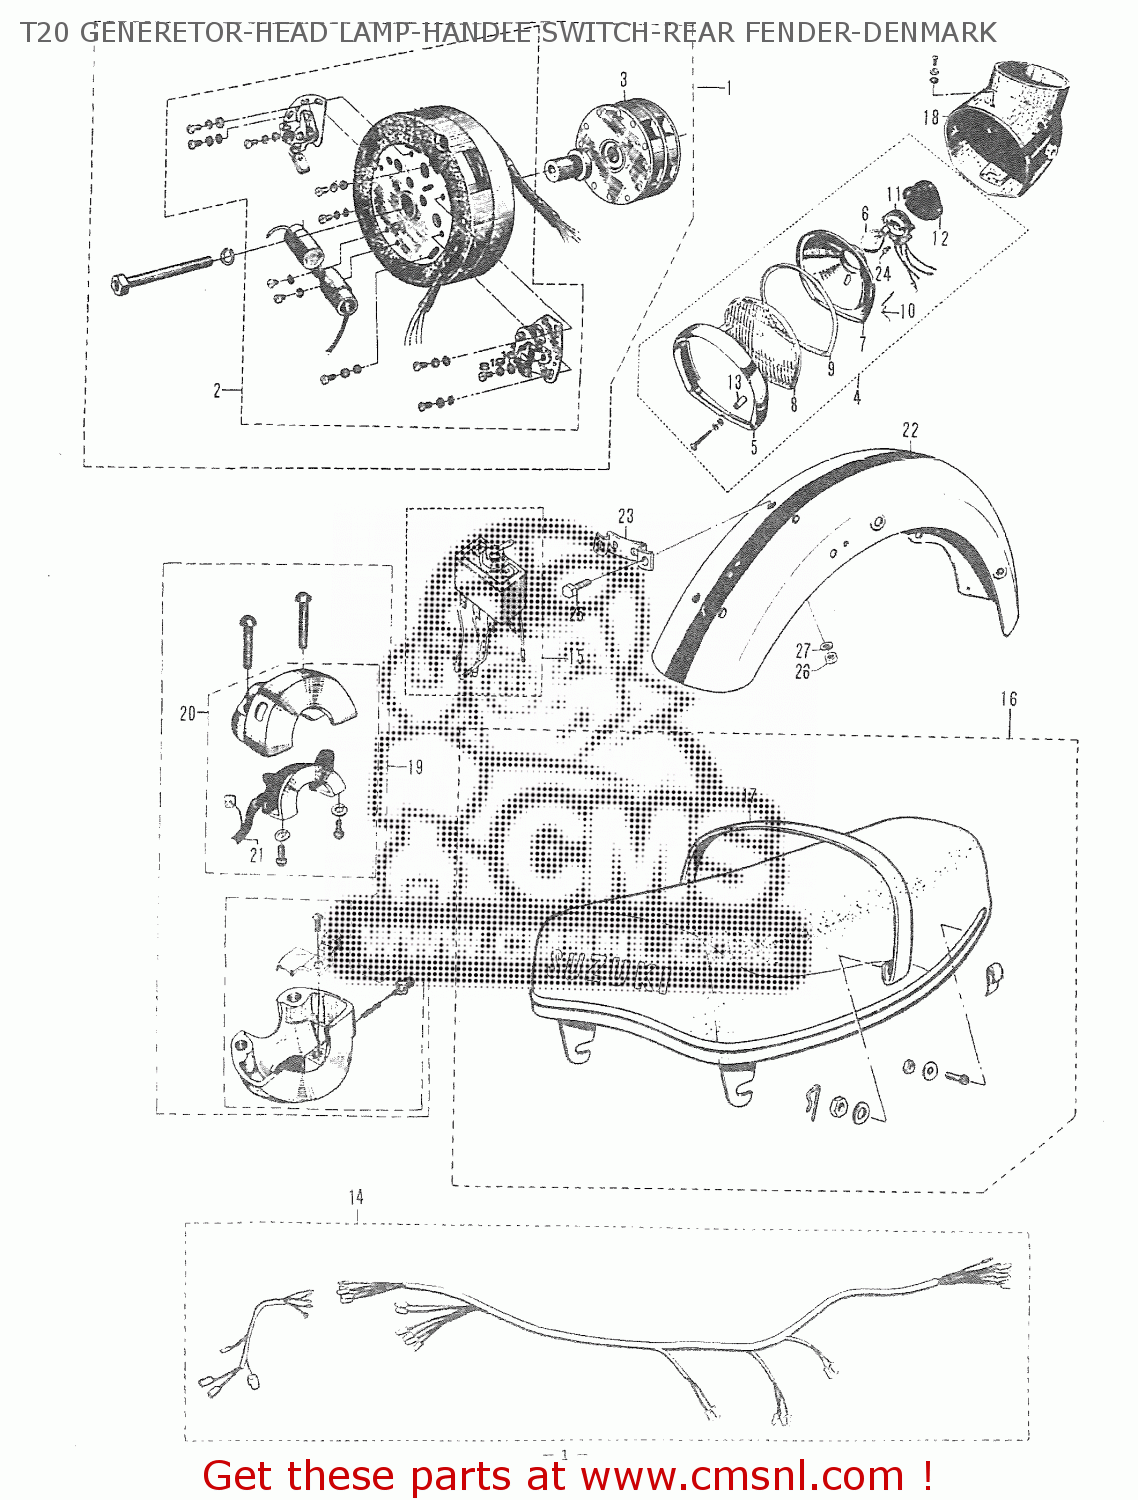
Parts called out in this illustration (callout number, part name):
1	A.C. GENERATOR ASS'Y
2	STATOR ASS'Y
3	ROTOR
4	HEAD LAMP ASS'Y
5	HEAD LAMP RIM
6	HEAD LAMP BULB
7	HEAD LAMP REFLECTOR
8	HEAD LAMP LENS
9	HEAD LAMP LENS GASKET
10	SPRING,HEAD LA
11	HEAD LAMP BULB SOCKET
12	HEAD LAMP SOCKET RUBBER CAP
13	HEAD LAMP RIM FITTING SPACER
14	MAIN WIRING HARNESS ASS'Y
15	CITY LAMP SWITCH ASS'Y
16	DUAL SEAT ASS'Y
17	DUAL SEAT PASSENGER STRAP
18	HEAD LAMP HOUSING
19	HANDLE SWITCH ASS'Y
20	HANDLE SWITCH UPPER COVER ASS'Y
21	WIRING HARNESS, SWITCH
22	REAR FENDER
23	REAR LICENCE PLATE HOLDER
24	BULB(12V3.4W,STANLEY,A72A)
25	HEXAGON BOLT
26	HEXAGON NUT
27	LOCK WASHER
